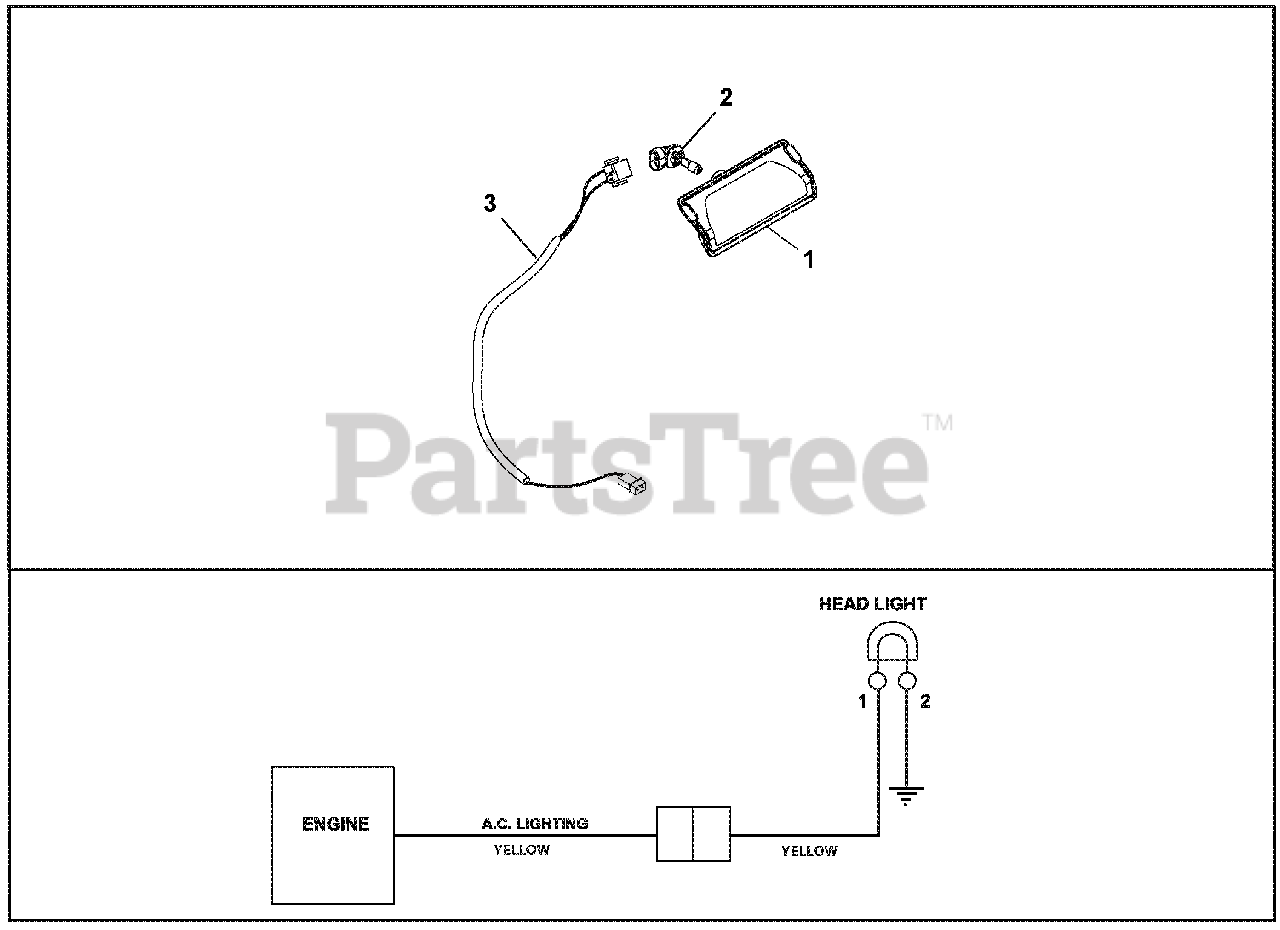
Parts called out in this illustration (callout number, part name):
1	HEADLIGHT ASSY, HALOGEN 20W
2	BULB, LIGHT-HALOGEN 20W
3	HARNESS, LIGHT - COMPACT
